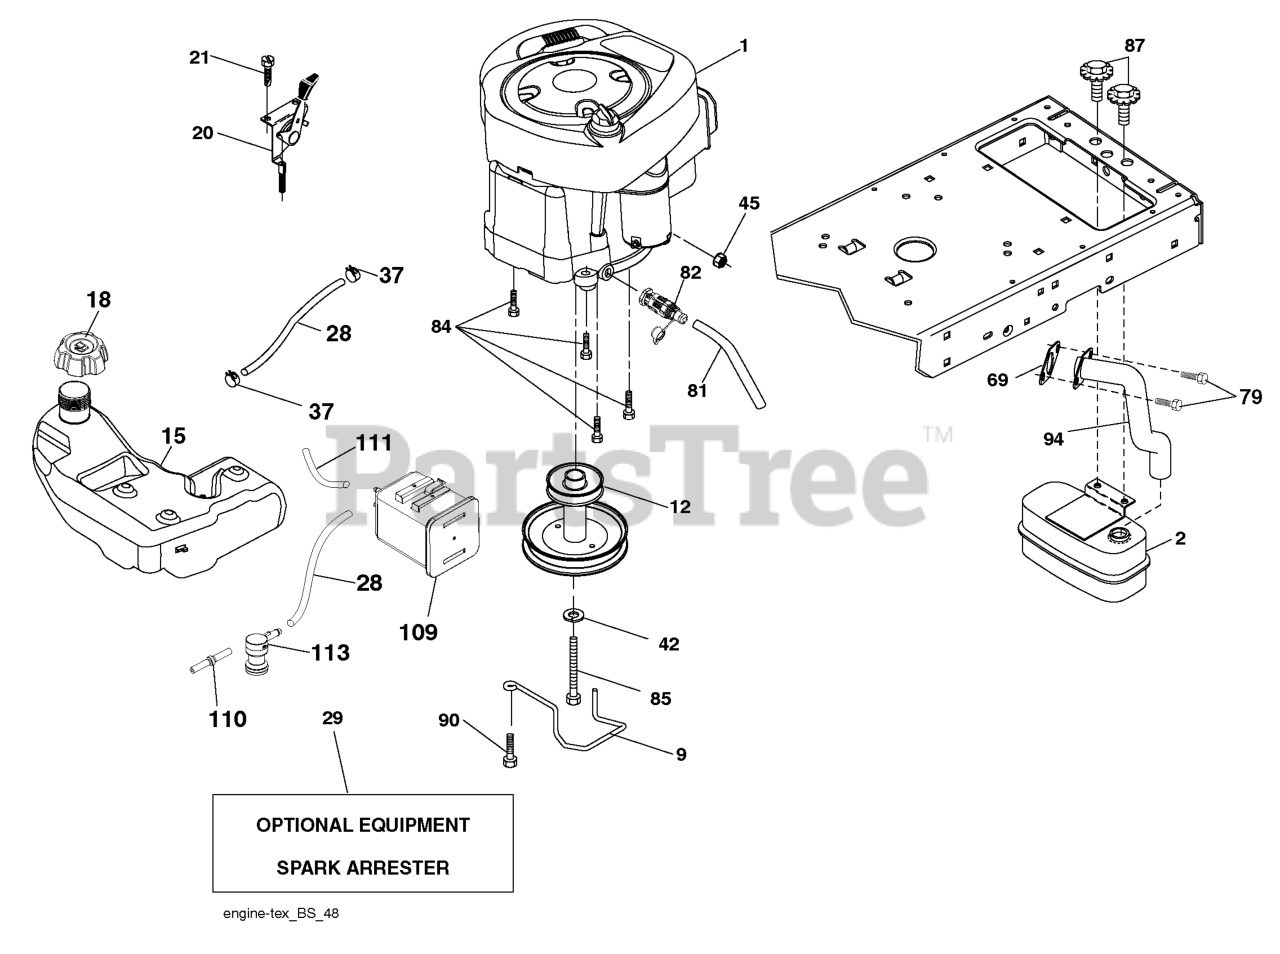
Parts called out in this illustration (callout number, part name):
2	MUFFLER.SINGLE.CYL.KOHL/B&S
9	KEEPER.BELT.ENGINE.4.2
12	PULLY ENGINE
15	TANK.ASM.FUEL.3GA.CARB
18	RP CAP ASM
20	CONTROL.TH/CK.COBRA.KO
21	SCREW.#10 X 0.750.BOS
28	LINE.FUEL.64"REAR.EMIS
29	KIT.SPARK ARRESTOR 794945 B&S
37	HOSE CLAMP
42	LOCKWASHER
45	NUT
69	REPL BY 532 27 22-93
79	SCREW.SOCKET HD.5/16-1
81	TUBE, DRAIN OIL ASM.
82	VALUE.OIL.DRAIN
84	SCREW.3/8-16
85	BOLT HEX 7/16-20X4-1/4"
87	BOLT.5/16-18UNCX3/4 W/SEMS.BLK
90	SCREW 3/8-16X1
94	EXHAUST.TUBE.B&S.
109	CANNISTER, CARBON
110	VALVE.ASM.ANTI-SLOSH
111	RP PURGE LINE
113	VALVE.SLANT.CARTRDG.90 DEG.TEX
